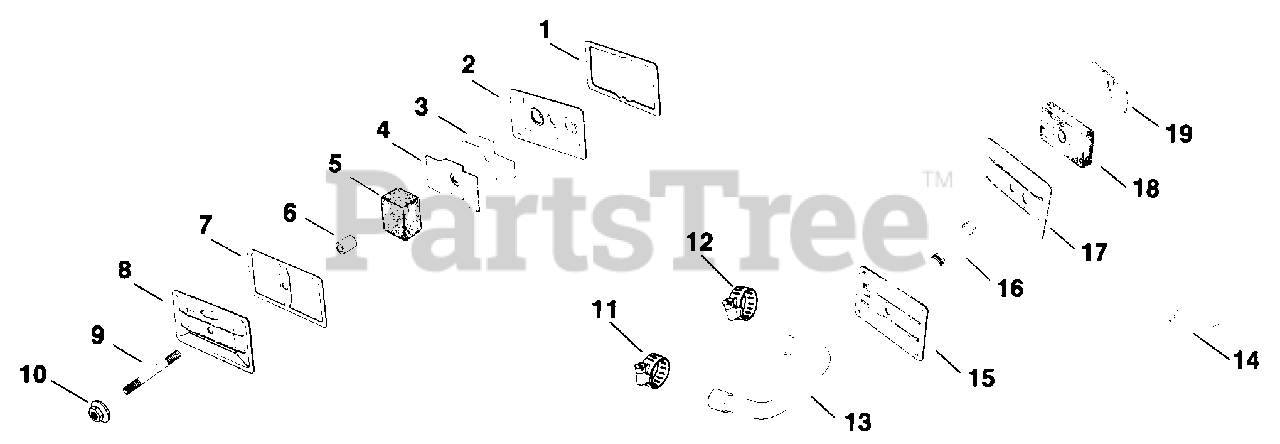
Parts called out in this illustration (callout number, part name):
1	GASKET, VALVE COVER
2	PLATE, BREATHER
3	REED, BREATHER - Use 47 402 01-S Breather Reed
4	BAFFLE, BREATHER
5	FILTER, BREATHER
6	SEAL, BREATHER
7	GASKET, VALVE COVER
8	KIT, COVER
9	STUD, 1/4-20x3-1/4" - DISCONTINUED
10	PALNUT, 1/4-20
